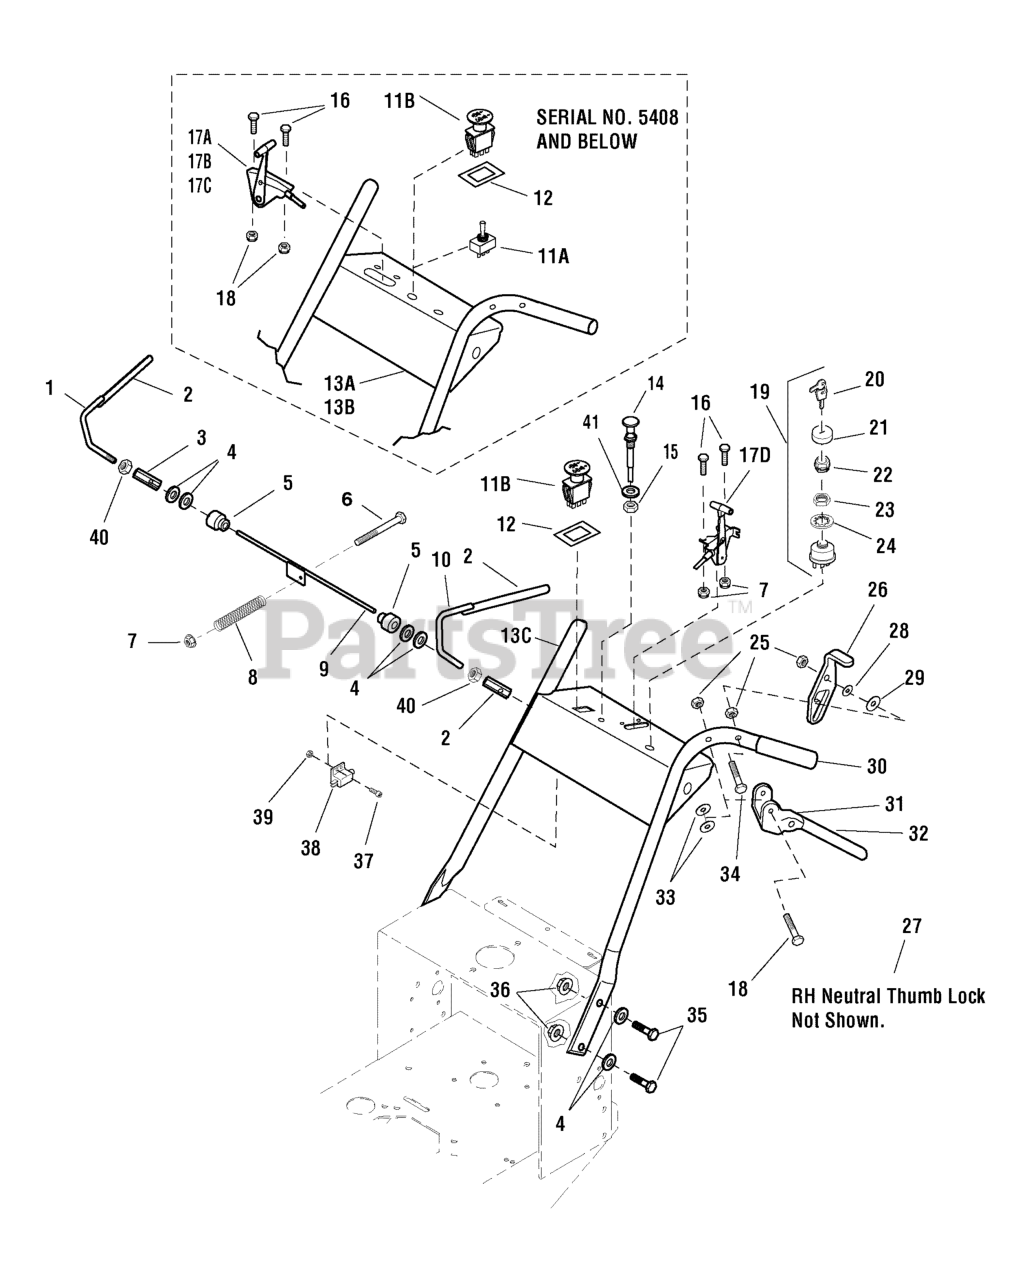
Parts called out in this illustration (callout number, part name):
1	OPERATOR PRESENCE HANDLE - RH
2	GRIP, VINYL, 1/2" X 4"
3	HEX ADJUSTER
4	WASHER, 3/8 SAE
5	SHOULDER BUSHING
6	BOLT, 1/4-20 x 3
7	NUT, 1/4-20 Hex Nylon Flange
8	SPRING, Compression
9	SWITCH ROD
10	OPERATOR PRESENCE HANDLE - LH
11A	SWITCH, Electric Clutch
11B	SWITCH, BLADE ENGAGEMENT
12	SWITCH RETAINER RING
13A	HANDLE BAR
13B	HANDLE BAR
13C	HANDLE BAR
14	CABLE, Choke Control
15	NUT, 3/8-24 Hex
16	HHCS, 1/4-20 X 0.625, GR5, ZINC/CLEAR
17A	CABLE, Throttle, 38"
17B	CABLE, Throttle, 54"
17C	CABLE, Throttle, 45"
17D	CABLE, Throttle Control, 46"
18	BOLT, 5/16-18 x 2-1/2
19	SWITCH, Ignition, Complete
20	KEY, IGNITION MOLDED SET
21	COVER, PLASTIC, SNAP ON
22	PLASTIC NUT
23	STEEL NUT
25	NUT, 5/16-18 Hex Nylon Flange
26	NEUTRAL THUMB LOCK, LH
28	WASHER, Belleville, 5/16
29	WASHER, 5/16" SAE
30	GRIP, FOAM, .940" X 4.62" X .187"
31	BRAKE LEVER
32	GRIP, Brake Lever
33	WASHER, Nylon, 5/16
34	BOLT, 5/16-18 X 2
35	BOLT, 3/8-16 X 1-1/4" GD5 CZ
36	NUT, 3/8-16 Hex Serrated Flange
37	SCREW, #10-24 x 1/2
38	SWITCH, PLUNGER, N.C.
39	NUT, #10-24 Hex
40	NUT, 3/8-16 Hex
41	WASHER, 3/8, Lock
